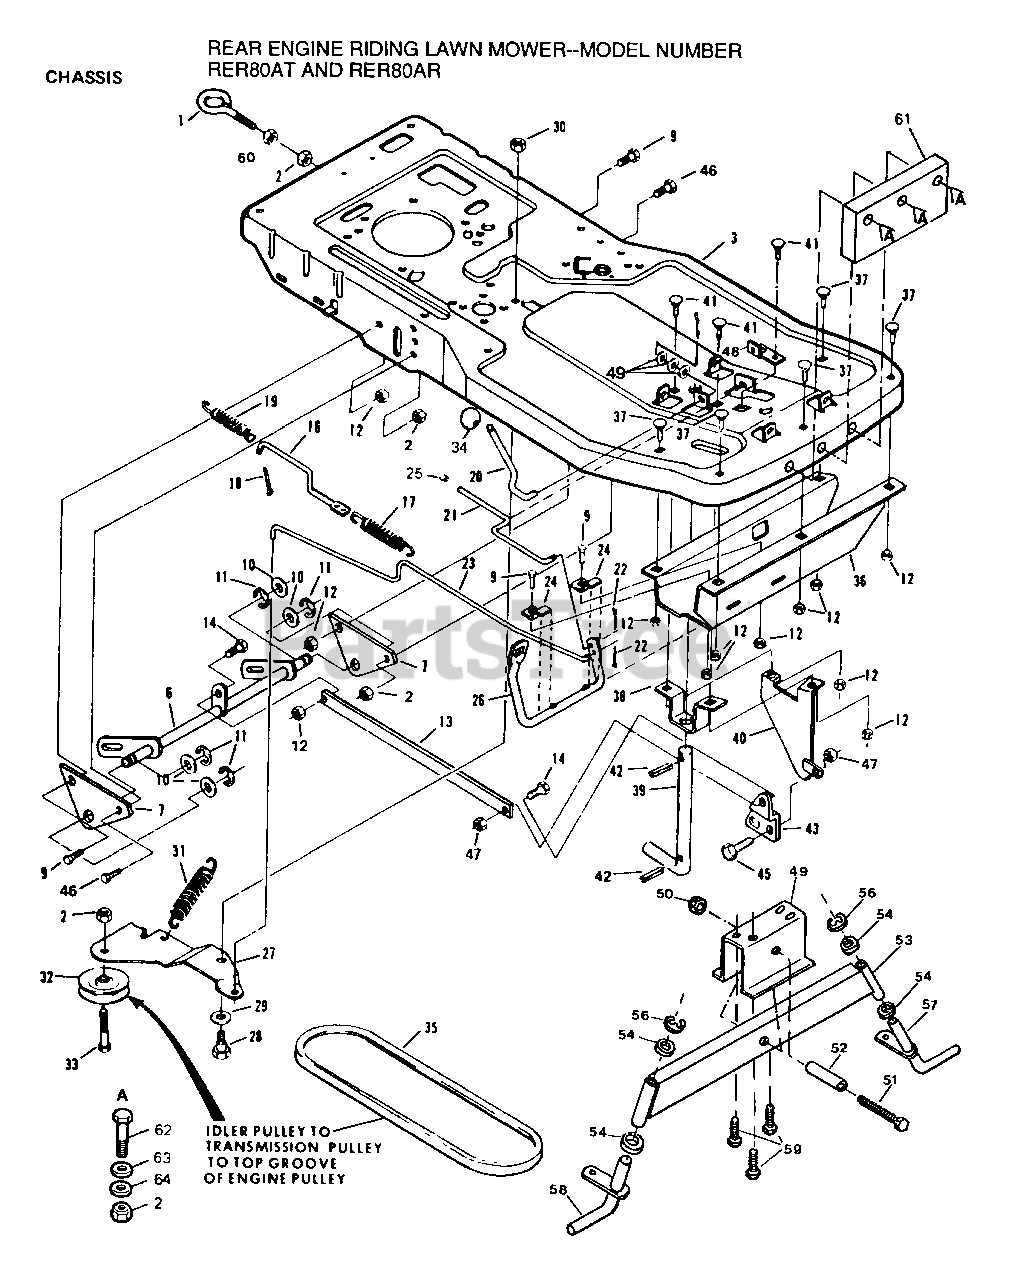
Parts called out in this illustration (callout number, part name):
1	TOW HITCH - EYEBOLT
9	BOLT
10	WASHER LT
13	PARALLEL BAR
22	COTTER PIN
25	PLUNGER CAP T
28	BOLT SHOULDER LT
30	NUT
32	IDLER PULLEY RER
35	V BELT T (L439)
36	FRONT MEMBER RER
37	BOLT
38	LIFTER BRKT T
41	BOLT
42	DRIVELOKPINTYPE
43	"RER, BELLCRANK"
47	NUT
48	PIVOT BRKT RER
50	NUT LTV
51	SPEC BOLT RER
52	TUBE - SUPPORT
53	AXLE ASSY RER
54	BUSHING
59	SCREW
60	NUT
61	COUNTERWEIGHT R
62	BOLT
63	WASHER
64	WASHER
